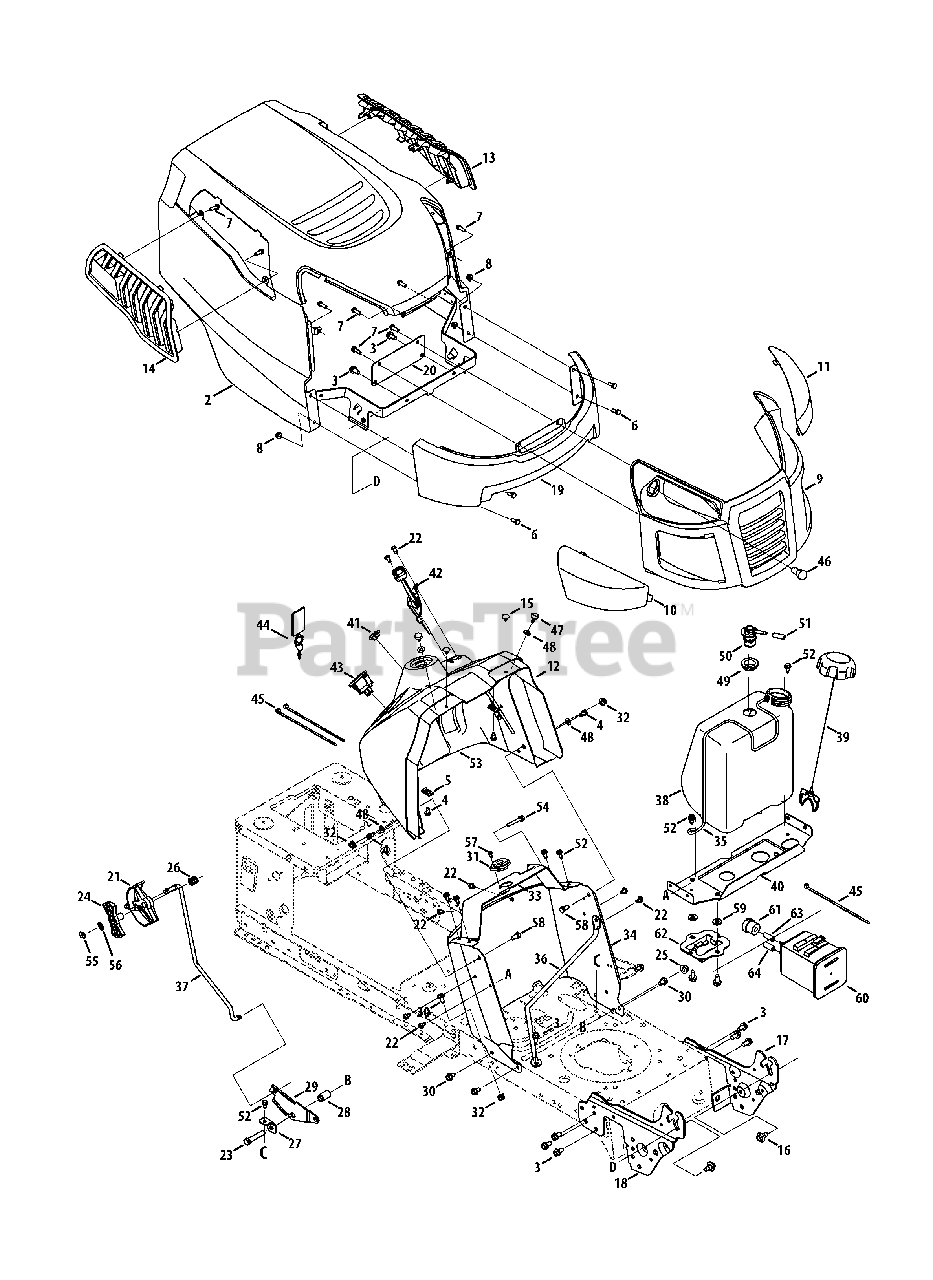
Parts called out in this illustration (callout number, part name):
1	Bulb Socket
2	Hood Assembly
3	Screw, 5/16-18 x .750
4	Hex Washer Screw, 1/4-20 x .500
5	Tin Clip Nut, 1/4-20
6	SCREW 1/4-20 x .620 GR5
7	Screw, 1/4 x .750
8	Nut, Hex Flange Insert Lock, 1/4-20
10	Headlight Lens, RH
11	Headlight Lens, LH
12	Dash Collar
13	Hood Scoop, LH
14	Hood Scoop, RH
15	Bumper
16	Shoulder Screw, 5/16-18
17	Left Support Pivot Bracket
18	Right Support Pivot Bracket
19	Lower Grill
20	Lower Grill Bracket
21	Parking Brake Lever
22	Self-Tap Screw, 1/4-20
23	Hex Head Screw, 3/8-16
24	Ferrule, 1/4-20 x 1.00
25	Nut, Hex Flange Insert Lock, 3/8-16
26	Compression Spring
27	Speed Latch Support Tab
28	Flange Spacer
29	Speed latch
30	Self-Tap Screw, 5/16-18
31	Steering Column Bearing
32	Nut, Hex Flange Lock, 5/16-18
33	Steering Support Bracket
34	Dash
35	Fuel Tank Support Rod
36	Dash support Rod
37	Control Rod
38	Fuel Tank
39	Fuel Cap
40	Gas Tank Support Bracket
41	Choke Plug
42	Throttle/Choke Assembly
43	Key Switch Module
44	Key Assembly
45	Cable Tie
46	Headlight Bulb
47	Ratchet Clip, .250 x .500
48	Flat Washer, .25 x .630 x .0515
49	Rubber Grommet
50	Fuel Rollover Valve
51	Vent Hose
52	Hex Washer Screw, 1/4-20 x .625
53	Upper Dash
54	Hex Flange Bolt
55	Top Lock Weldnut
56	Lock Washer
57	Screw, #10
58	Hex Head Screw, 5/16-18
59	Flat Washer
60	Carbon Cannister
61	Cannister Vent Filter
62	Cannister Adapter Bracket
63	Low Perm. Fuel Hose, 3/16 White
64	Low Perm. Fuel Hose, 7/32 Yellow
